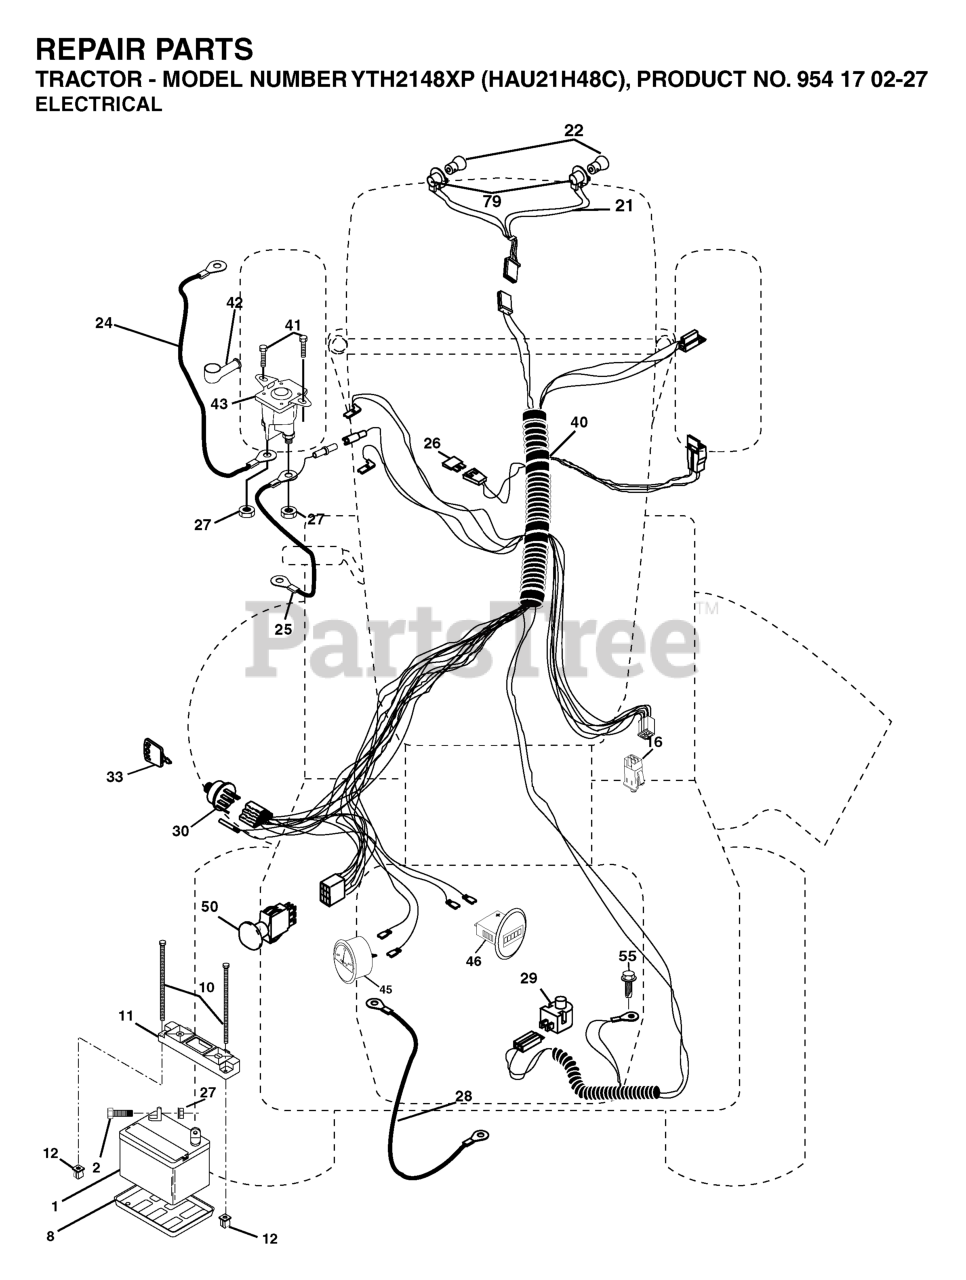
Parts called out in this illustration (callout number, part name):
1	BATTERY 12V .35 AMP
2	BOLT.HEX.1/4.X.3/4.DICHROMATE
8	BATTERY TRAY T
10	BOLT 1/4-20 X 7.5
11	BATTERY HOLDDOWN FRONT MOUNT
12	NUT, PUSH NYLON 1/4" BATTERY
16	SWITCH INTERLOOK PUSH-IN
21	HARNESS.W/LIGHT SOCKET
25	CABLE BATTERY 6 GA 22" W/16W
26	FUSE 20AMP
27	NUT
28	CABLE GROUND 6 GA 21" 90T BLK
29	RP.SWITCH.PLUNGER.NC.GRAY
30	IGNITION SWITCH
33	KEY MLD GEN DELTA
41	SCREW
42	TERMINAL COVER
43	SOLENOID
45	RP AMMETER.ROUND.SILVER.DELTA
46	RP HOURMETER SNAP-IN
50	RP.PTO.SWITCH.8 TERMINAL.BLACK
55	Screw 5/16-18 x 1/2 Hex, Self Tapping 5/16-18 x 1/2
79	BULB HOLDER ASM.
